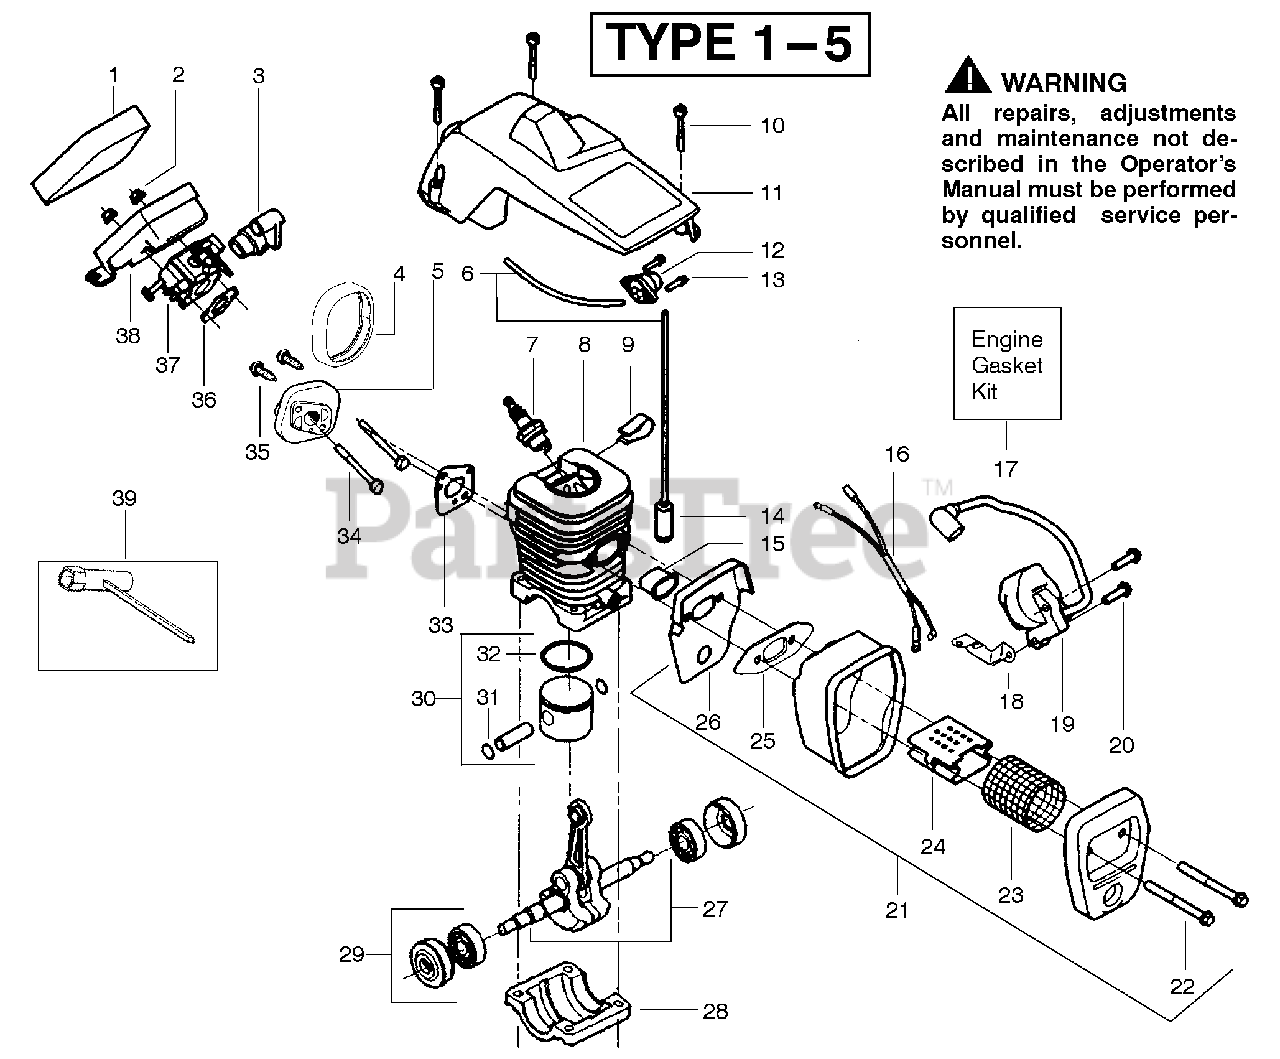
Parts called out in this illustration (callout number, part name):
1	Foam- Air Filter
3	Grommet-Carb Adjust
4	Seal-Carb Adapter
5	Carb. Adapter
6	Fuel Line Kit
7	Spark Plug
8	Cylinder Kit
9	Clip-High Tension Lead
11	Cylinder Shield
12	Air Purge Ass’y.
14	Fuel Pick-up Ass’y.
15	Heat Insulator
16	Assy. -Wire Harness
17	Kit-Engine Gasket
18	Strap-Ground
19	Module- Ignition
21	Assy-Muffler
23	Screen-Spark
24	Diffuser-Muffler
25	Gasket-Muffler
26	Backplate-Muffler
27	Assy. - Crankshaft
28	Cap-Crankcase
29	Assy.-Seal & Bearing
30	Kit-Piston
31	Retainer-Piston Pin
32	Ring - Piston
33	Gasket - Carb. Adapter
36	Gasket - Carburetor
37	Kit-Carburetor
38	Housing- Air Filter
39	Wrench - Bar
